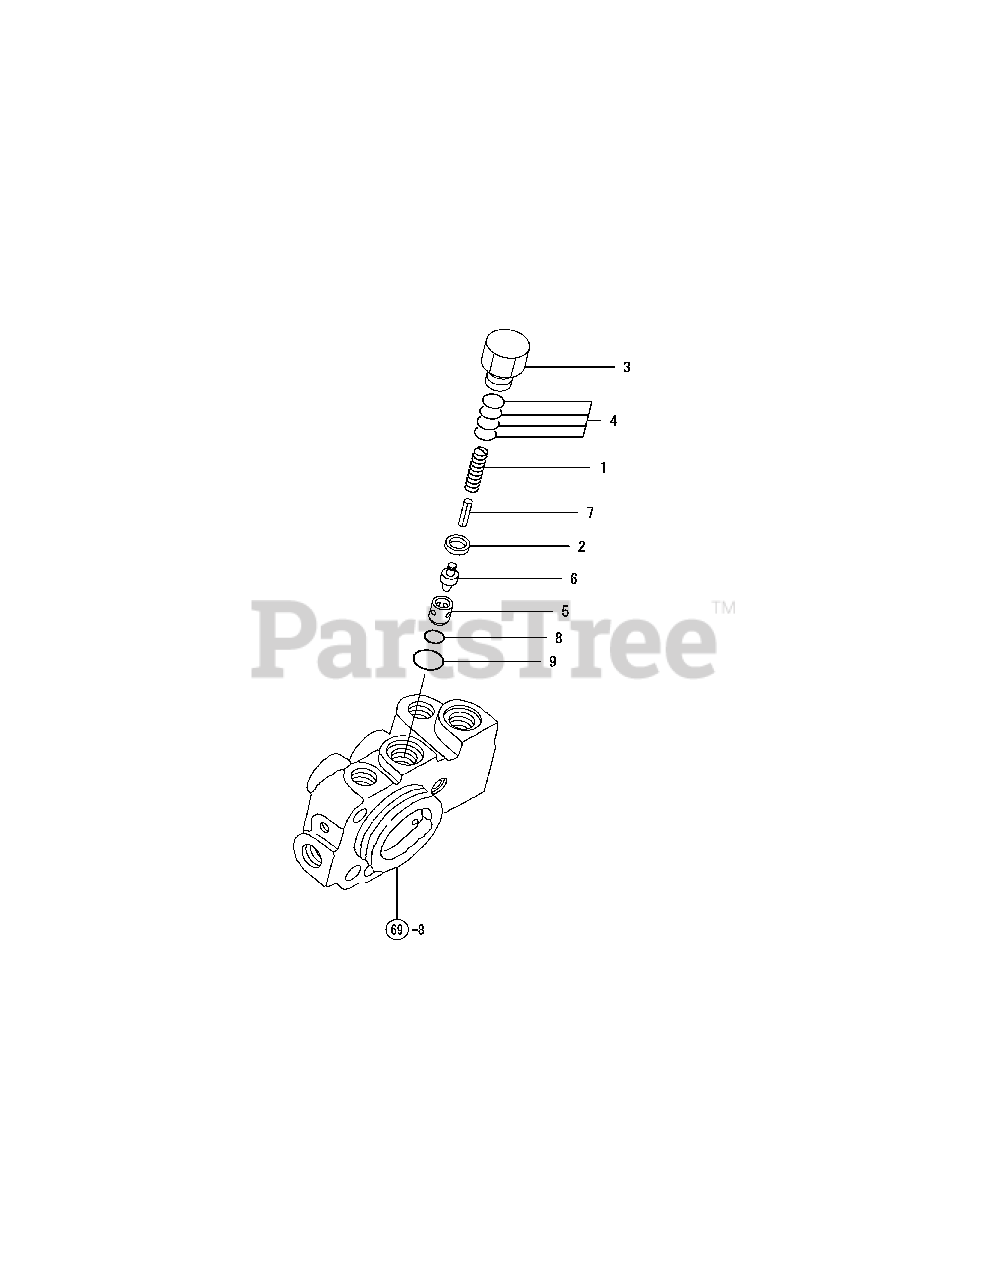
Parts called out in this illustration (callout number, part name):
1	SPRING, RELIEF VALVE
3	PLUG, SAFETY VALVE
5	SEAT, SAFETY VALVE
6	POPPET, SAFETY VALVE
7	SPRING PIN 6X28
8	O-RING 1A P 12.0
9	O-RING 1A P-18.0
